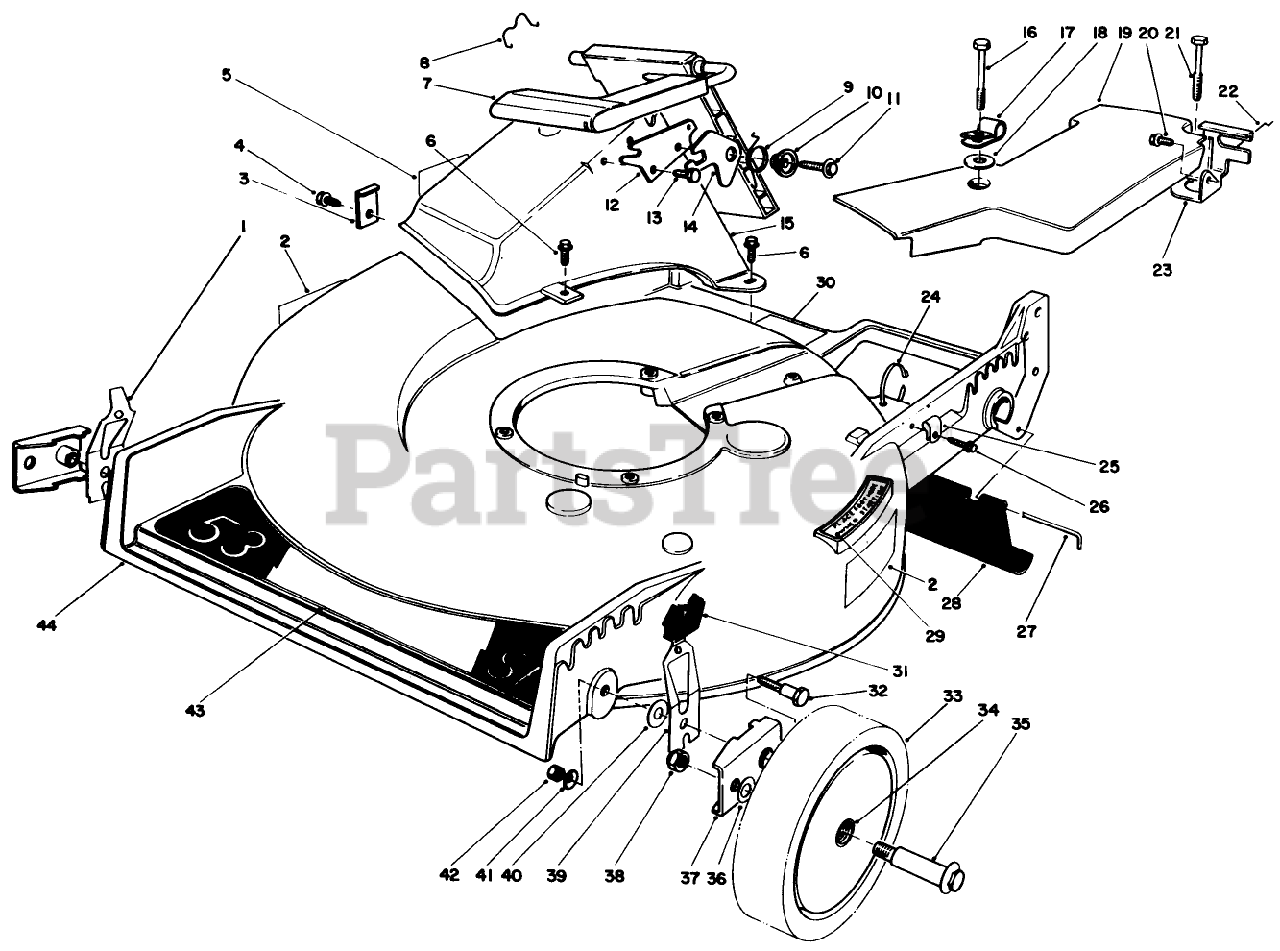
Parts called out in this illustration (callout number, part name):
3	TUNNEL CLIP
4	SCREW
6	SCREW-HWH
8	DOOR RET SPRING
9	TORSION SPRING
10	DOOR SPACER
11	SCREW-HWH
12	DOOR LATCH PLATE
13	SCREW-PLASTITE
14	SAFETY LATCH
16	SCREW-SPECIAL
17	CLAMP-CABLE
18	WASHER
20	SCREW-THD ROLL, HWH
21	SCREW-HWH
22	RETAINER-CABLE
24	TIE-CABLE
25	CLAMP-CABLE
26	SCREW
27	ROD-SHIELD
29	DECAL - STEP PAD INT'L
31	KNOB-ARM
32	PIVOT SCREW
34	BUSHING
35	WHEEL BOLT
36	WASHER
37	HP PIVOT ARM ASM
40	WASHER-PIVOT
41	WASHER-BELLEVILLE
42	NUT-LOCK, NI
